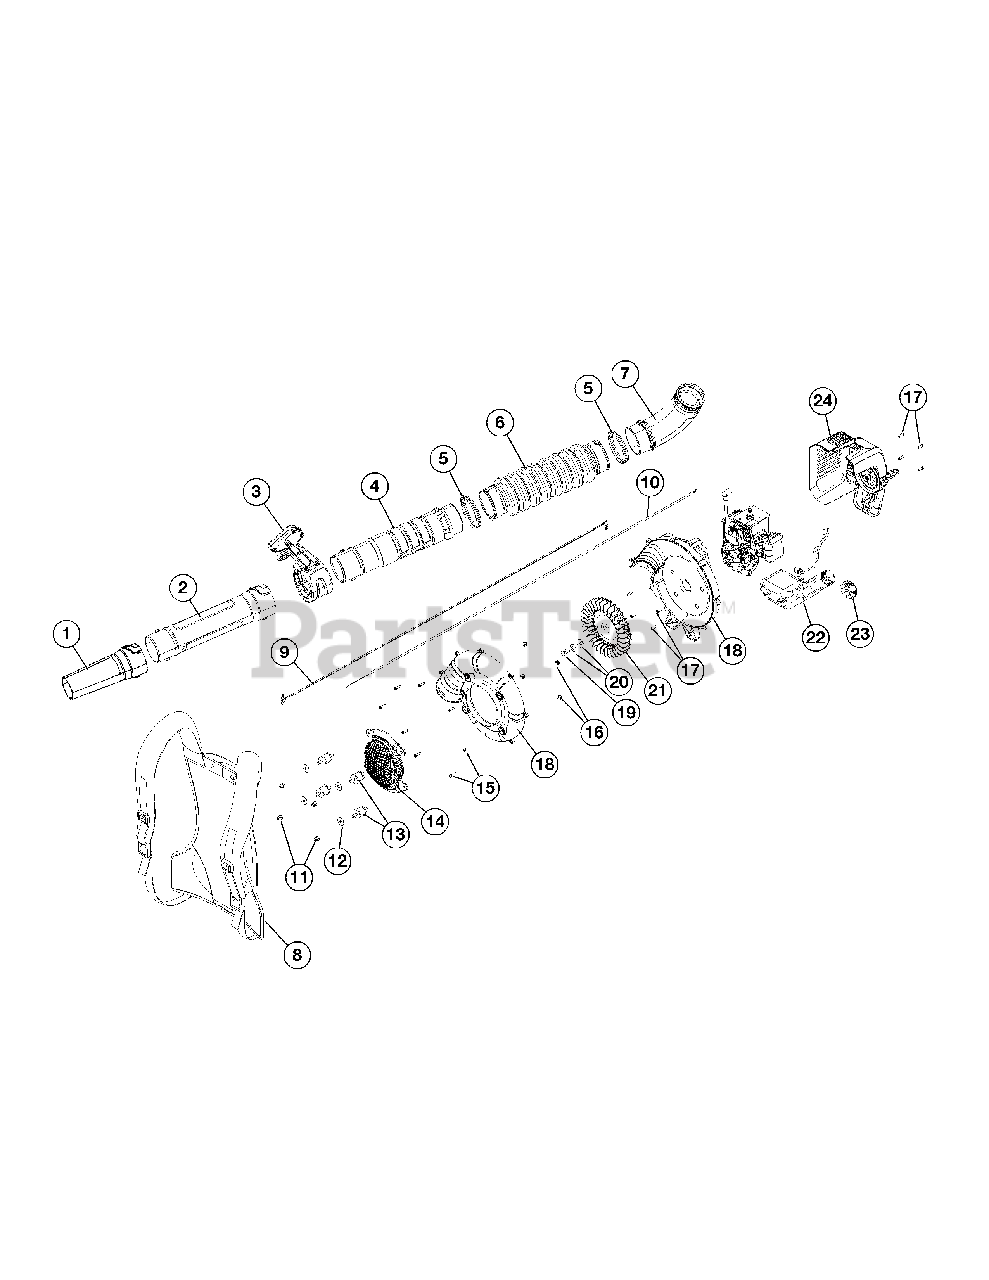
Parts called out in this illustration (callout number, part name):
2	Lower Blower Tube
3	Throttle Grip Assembly
4	Upper Blower Tube
8	Harness
10	Throttle Cable
11	Nut
12	Spacer
13	Insulator Mount
14	Intake Cover
16	Nut
17	Screw
18	Impeller Housing Assembly (Incl. Ref No. 13 & 15-17)
20	Impeller Hardware (Incl. Ref No. 19)
21	Impeller (Incl. Ref No. 19 & 20)
22	Fuel Tank Assembly (Incl. Ref No. 23)
24	Starter Housing Assembly (Incl. Ref No. 17)
